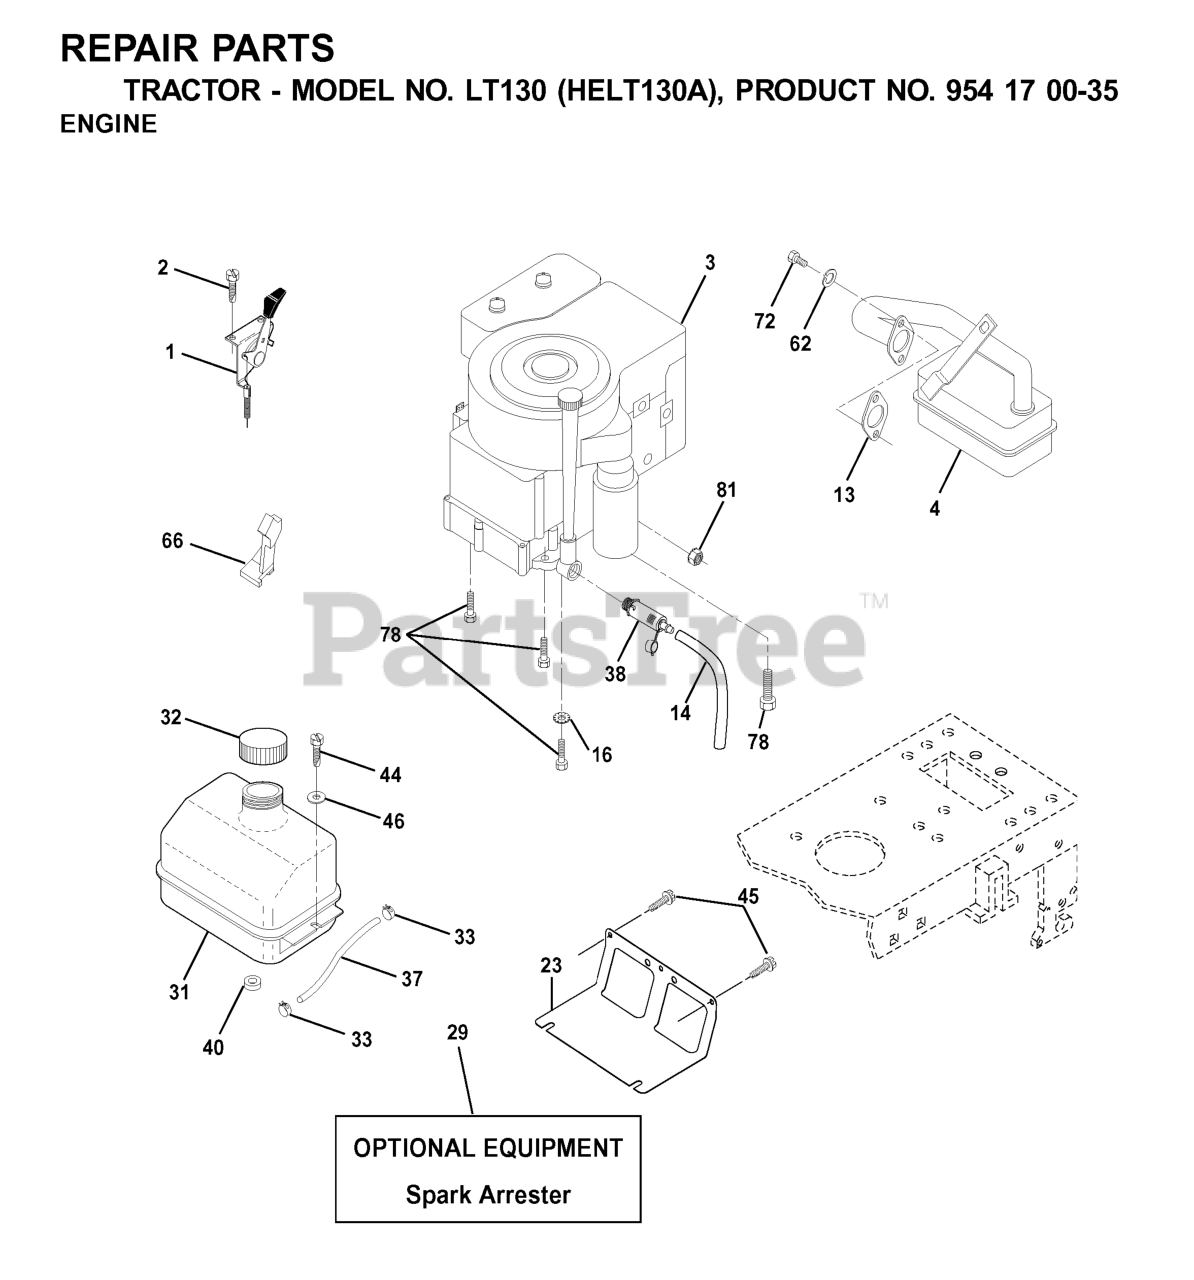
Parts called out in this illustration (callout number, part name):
1	THROTTLE.CONTROL.CABLE.BLACK
2	SCREW LT
4	MUFFLER.SINGLE.B&S.10-12HP
13	REPL BY 532 27 22-93
14	TUBE, DRAIN OIL ASM.
16	LOCKWASHER
23	SHIELD.BROWNING.DBR.GUARD
29	KIT.SPARK ARRESTOR 794945 B&S
31	TANK FUEL LT
32	FUEL CAP
33	HOSE CLAMP
37	LINE.FUEL.20
38	PLUG, OIL DRAIN EASY
40	BUSHING.SNAP.NYL.BLK.
44	SCREW HEXWSHR 1/4-20X3/4
45	SCREW, 3/8-16X3/4
62	WASHER.LOCK.HVY.HLCL.SPR.5/16
66	STOP THROTTLE
72	SCREW
78	SCREW.3/8-16
81	NUT
